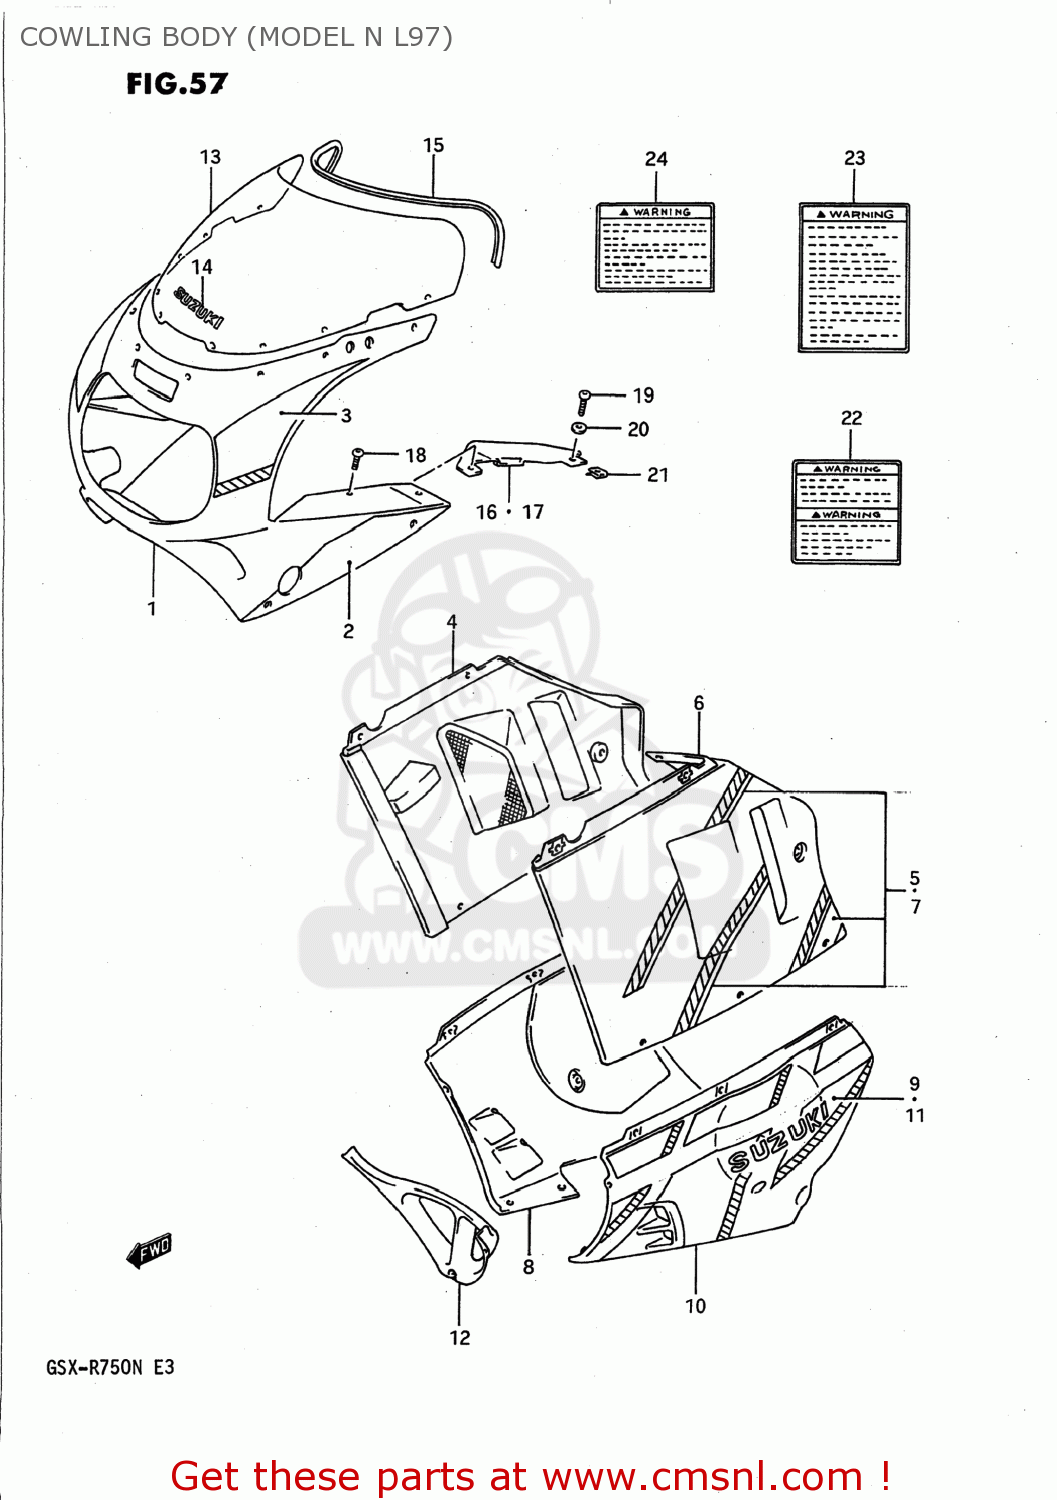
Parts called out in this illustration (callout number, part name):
1	BODY ASSEMBLY,COWLING
2	TAPE SET,COWLING,UPPER SIDE
3	TAPE SET,COWL UPR FR
4	COVER COMP,COWLING SIDE,RIGHT
5	TAPE SET,COWLING SIDE,RIGHT
6	COVER,COWLING SIDE,LEFT (B
7	TAPE SET,COWL
8	COWLING COMP,UNDER,RIGHT
9	TAPE SET,COWLING,UNDER STRIPE
10	COWLING COMP,UNDER,LEFT
11	TAPE SET,COWL UNDER STRIPE,L
12	COWLING,UNDER,CENTER (B
13	SCREEN SET,WINDOW
14	EMBLEM,WINDSCREEN
15	MOLDING,WINDSCREEN
16	PANEL,COWLING UPR,R
17	PANEL,COWLING,UPPER,LEFT
18	SCREW(5X10)
19	SCREW(5X14)
20	WASHER(5.2X11X1)
21	NUT
22	LABEL (WARNING)
23	LABEL (WARNING SCREEN)
24	LABEL
